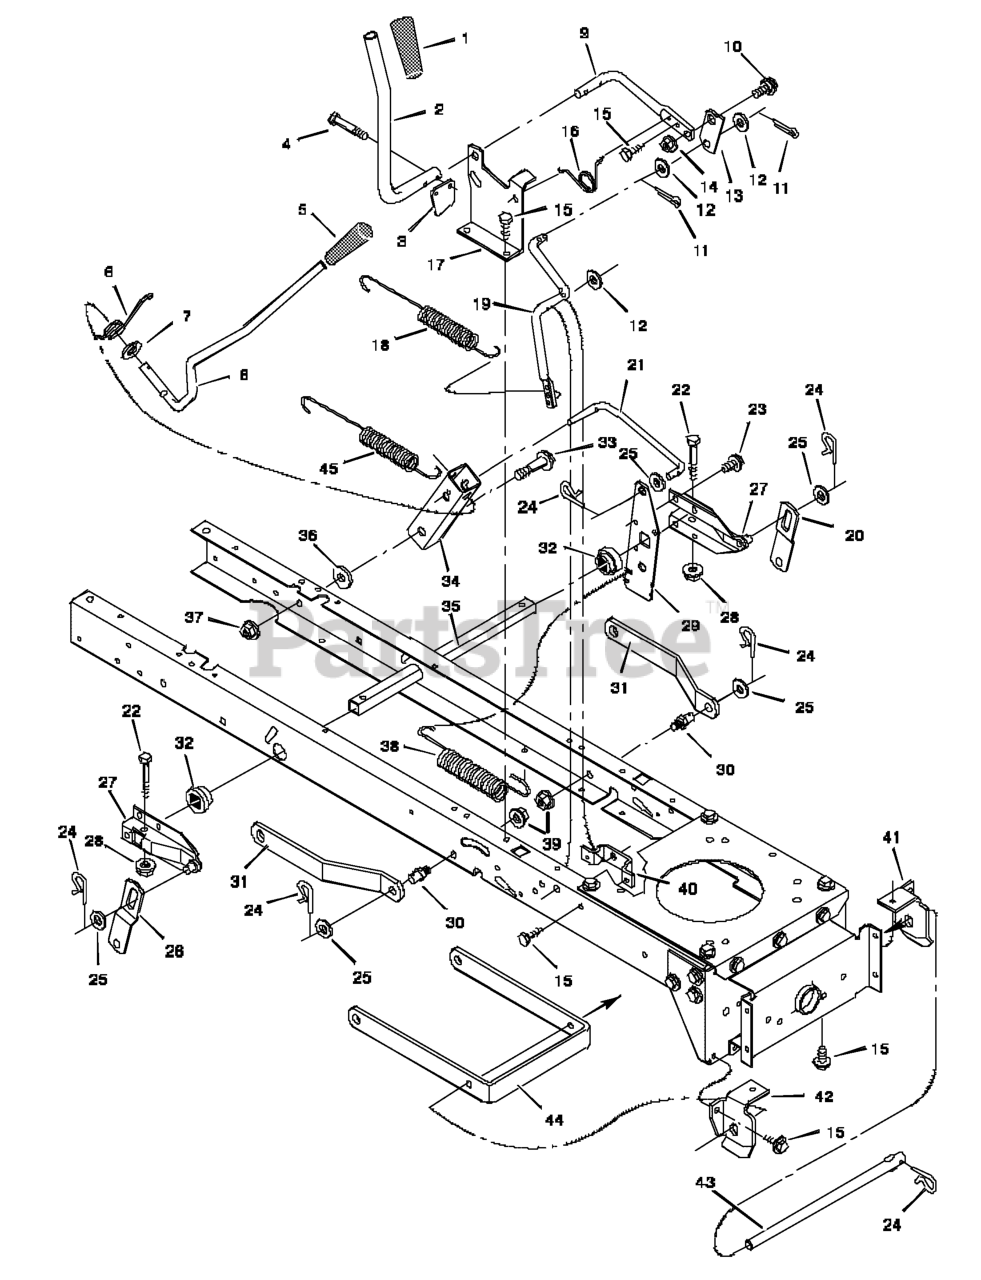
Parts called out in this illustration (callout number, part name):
1	Grip
3	Pad, Switch
4	Screw, Hex
5	Grip
8	Lever, Lift
9	Lever, PTO
10	Bolt, Shoulder
11	Pin, Cotter
13	Link, PTO
14	Nut, Flange
17	Bracket, PTO
19	Crank, PTO
20	Link, Left Lift
21	Link, Lift
24	Pin, Hair
26	Link, Right Lift
27	Lever Assembly, Lift
28	Nut, Flange
29	Plate, Lift Arm
30	Pin
31	Bracket, Rear Suspension
32	Bushing
33	Bolt, Shoulder
34	Bracket, Pivot
35	Tube, Deck Lift
37	Nut, Flange
39	Nut, Flange
40	Bracket, PTO
41	Hanger, Left Deck
42	Hanger, Right Deck
43	Rod, Hanger
44	Bracket, Suspension
